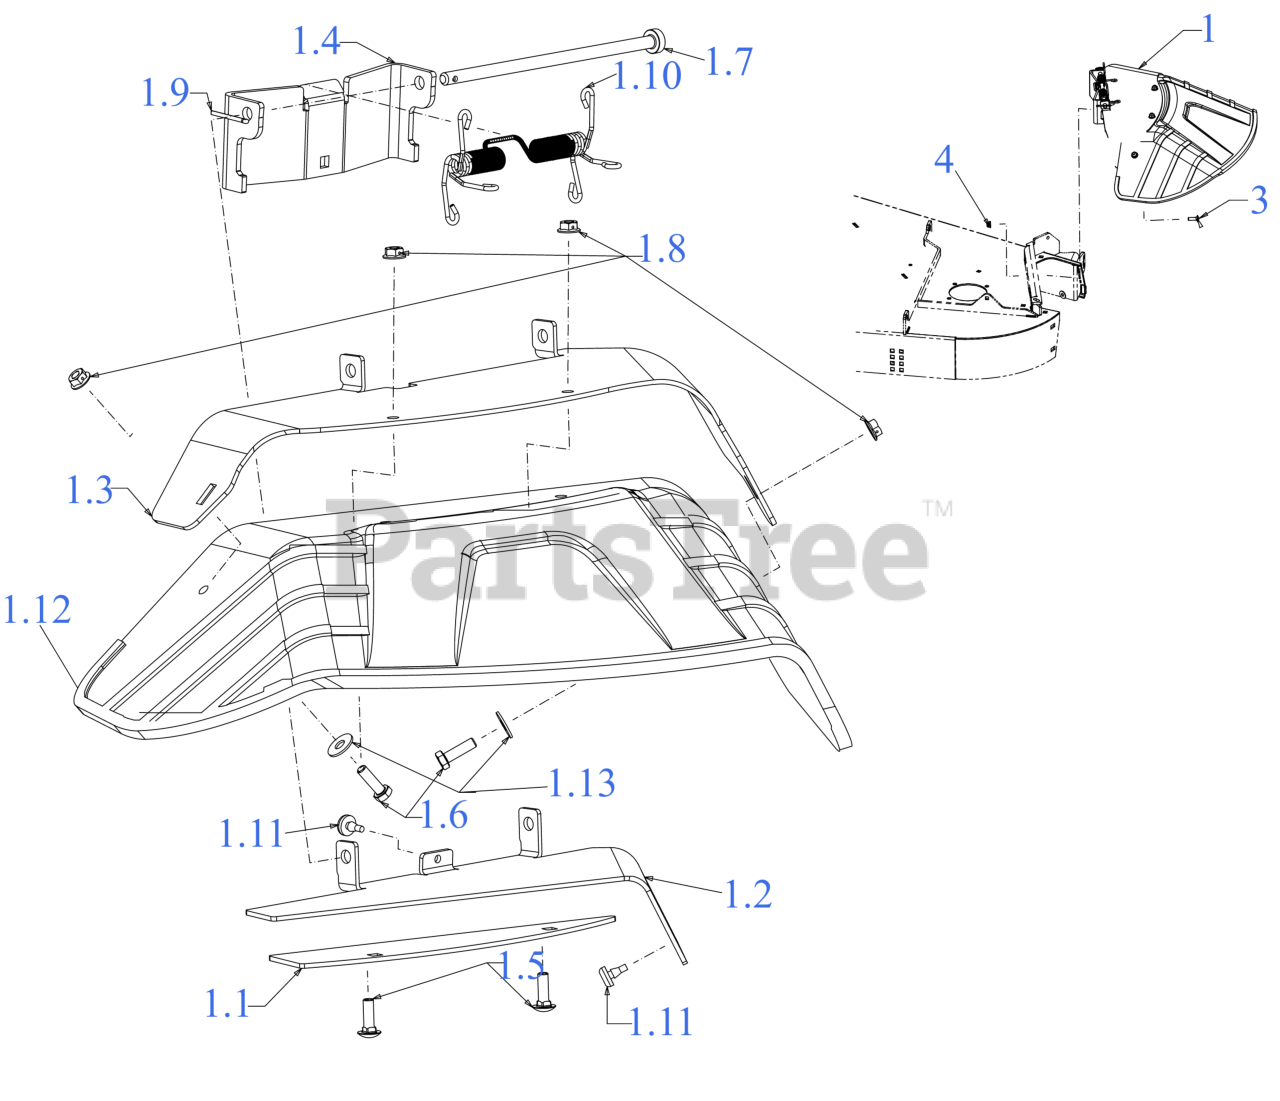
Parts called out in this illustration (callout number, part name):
1	DISCHARGE CHUTE
1.1	CHUTE BRACKET (BOTTOM)
1.2	CHUTE BRACKET (OPENING)
1.3	CHUTE BRACKET (TOP)
1.4	CHUTE BRACKET
1.5	CARRIAGE BOLT 5/16-18 x 1.00
1.6	SCREW 5/16-18 x 1.0 GR5
1.7	HINGE PIN .375 x 9.0
1.8	HEX FLANGE NUT
1.9	COTTER PIN
1.10	TORSION SPRING
1.11	RUBBER BUMPER
1.12	FIBER FORMED CHUTE
1.13	FLAT WASHER
3	CARRIAGE BOLT 5/16-18 x 1.00
4	FLANGE LOCK NUT 5/16-18
